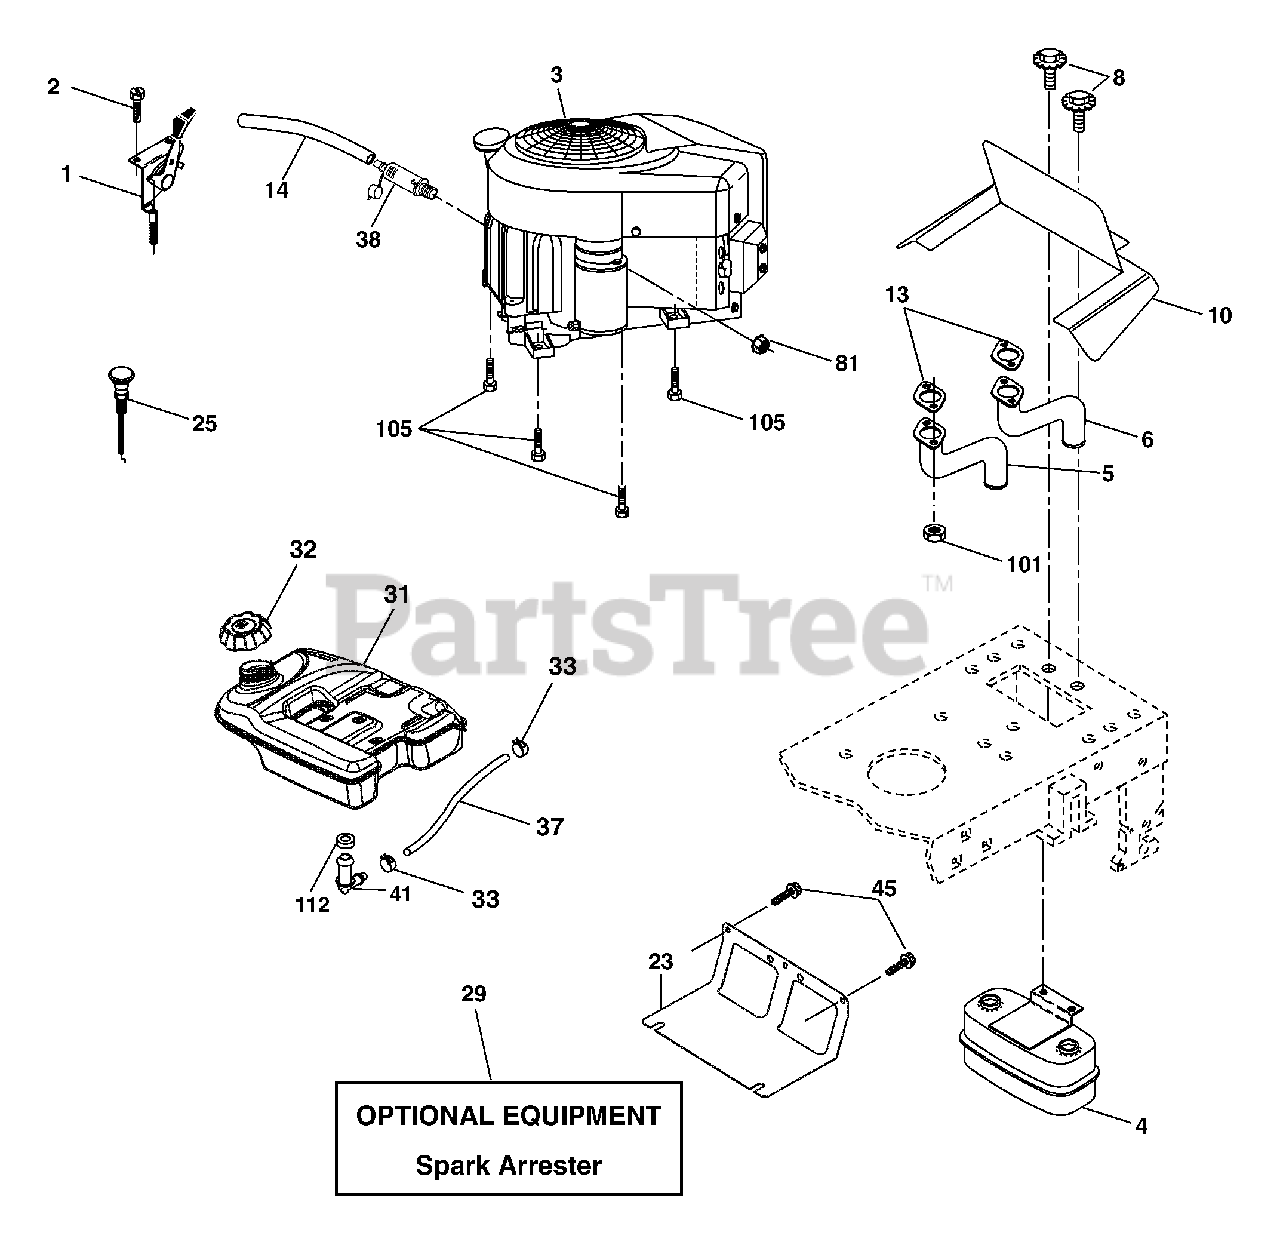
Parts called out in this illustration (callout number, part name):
1	Control, Throttle/Choke
2	Screw Hex Thd Cut 1/4-20 x 1/2
5	Exhaust Tube LH
6	Exhaust Tube RH
8	Bolt 5/16-18 unc x 3/4 w/Sems
10	Shield Heat Muffler
13	Muffler Gasket
14	Tube Oil Drain
23	Shield, Browning/Debris Guard
25	Control Choke
29	Arrester, Spark
31	Tank, Fuel
32	Cap, Fuel
33	Clamp, Hose Blk
37	Line, Fuel
38	Plug Drain Oil Easy
41	Stem Tank Fuel
45	Screw Hex Wsh Thdrol 3/8-16 x 3/4
81	Nut Keps Hex 1/4-20 unc
101	Nut Hex Flange Toplock M8-1.25
105	Screw 3/8-16 x 1
112	Bushing
